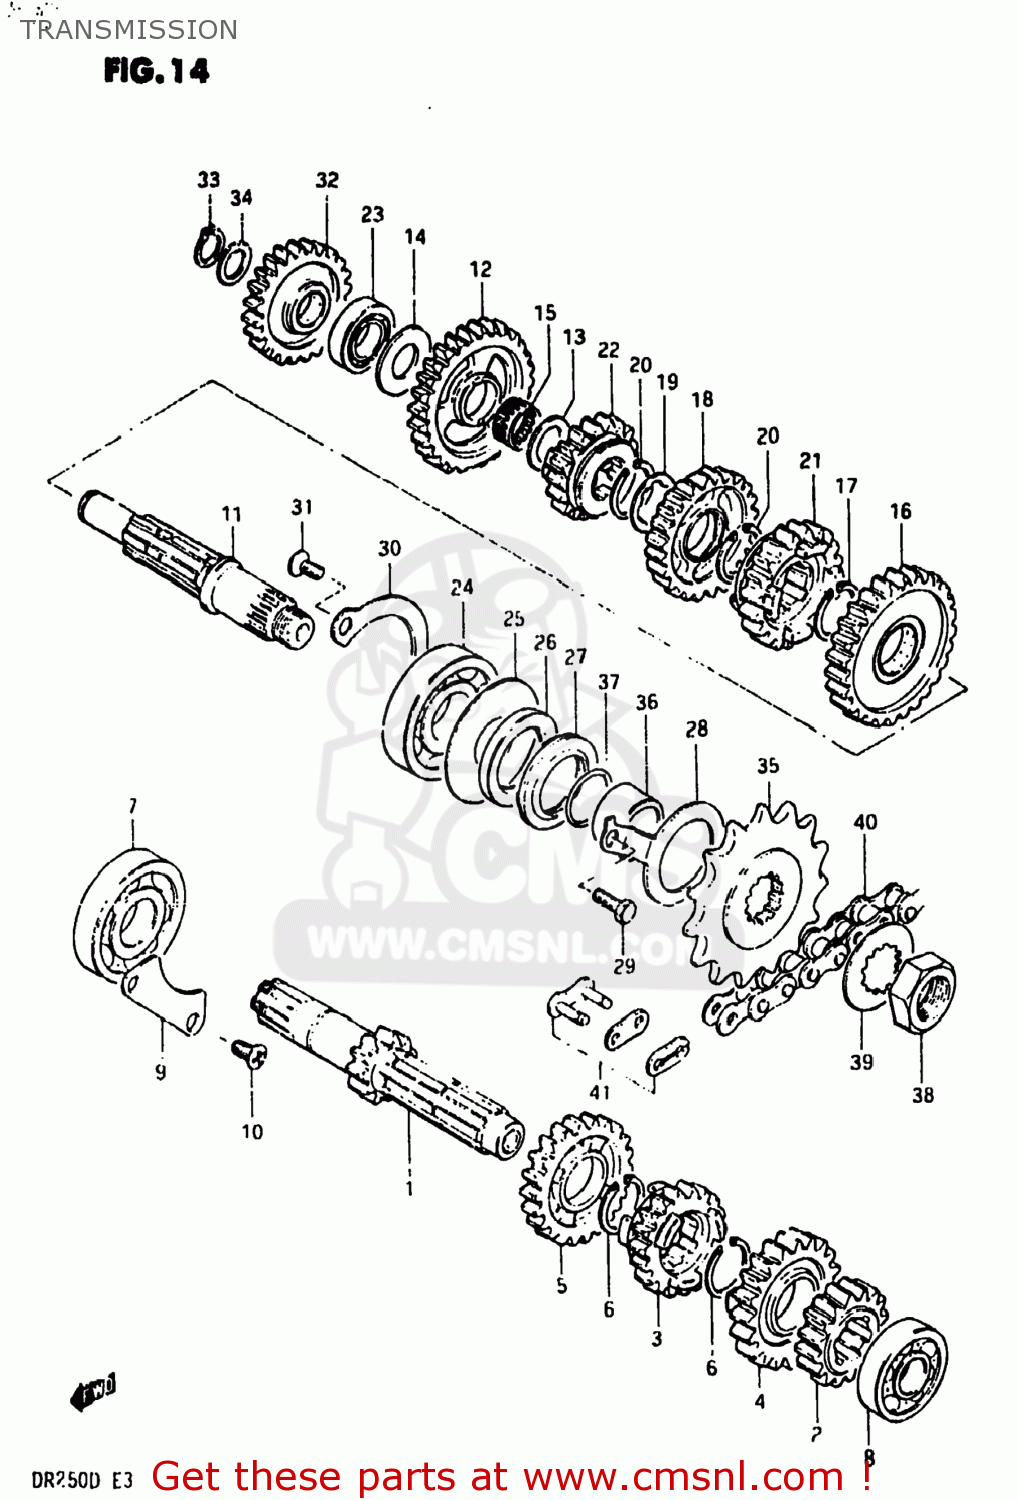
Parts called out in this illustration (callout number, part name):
1	SHAFT,COUNTER
2	GEAR,2ND DRIVE(NT:16)
3	GEAR,THIRD DRIVE (NT:19)
4	GEAR,FOURTH DRIVE
5	GEAR,FIFTH DRIVE
6	CIRCLIP
7	BEARING
8	BEARING
9	RETAINER,CNTR SHAFT BEARING
10	SCREW 6X12
11	SHAFT,DRIVE
12	GEAR,1ST DRIVEN(NT:29)
13	WASHER
14	WASHER
15	BEARING(17X21X9.8)
16	GEAR,SECOND DRIVEN
17	CIRCLIP
18	GEAR,THIRD DRIVEN
19	WASHER,LOCK
20	CIRCLIP
21	GEAR,FOURTH DRIVEN
22	GEAR,FIFTH DRIVEN
23	BEARING(17X36X12)
24	BEARING(22X56X16)
25	WASHER(35X55X1)
26	OIL SEAL (30X43X5)
27	OIL SEAL (30X43X7)
28	PLATE,DRIVESHAFT OIL
29	BOLT
30	RETAINER,DRIVE SHAFT BEARING
31	SCREW
32	GEAR,KICK STARTER IDLE(NT:24)
33	CIRCLIP
34	WASHER
35	SPROCKET,ENGINE
36	SPACER,ENGINE SPROCKET
37	O RING(D:2.5,ID:21)
38	NUT
39	WASHER,LOCK
40	CHAIN ASSEMBLY,DRIVE
41	JOINT ASSEMBLY,CHAIN
